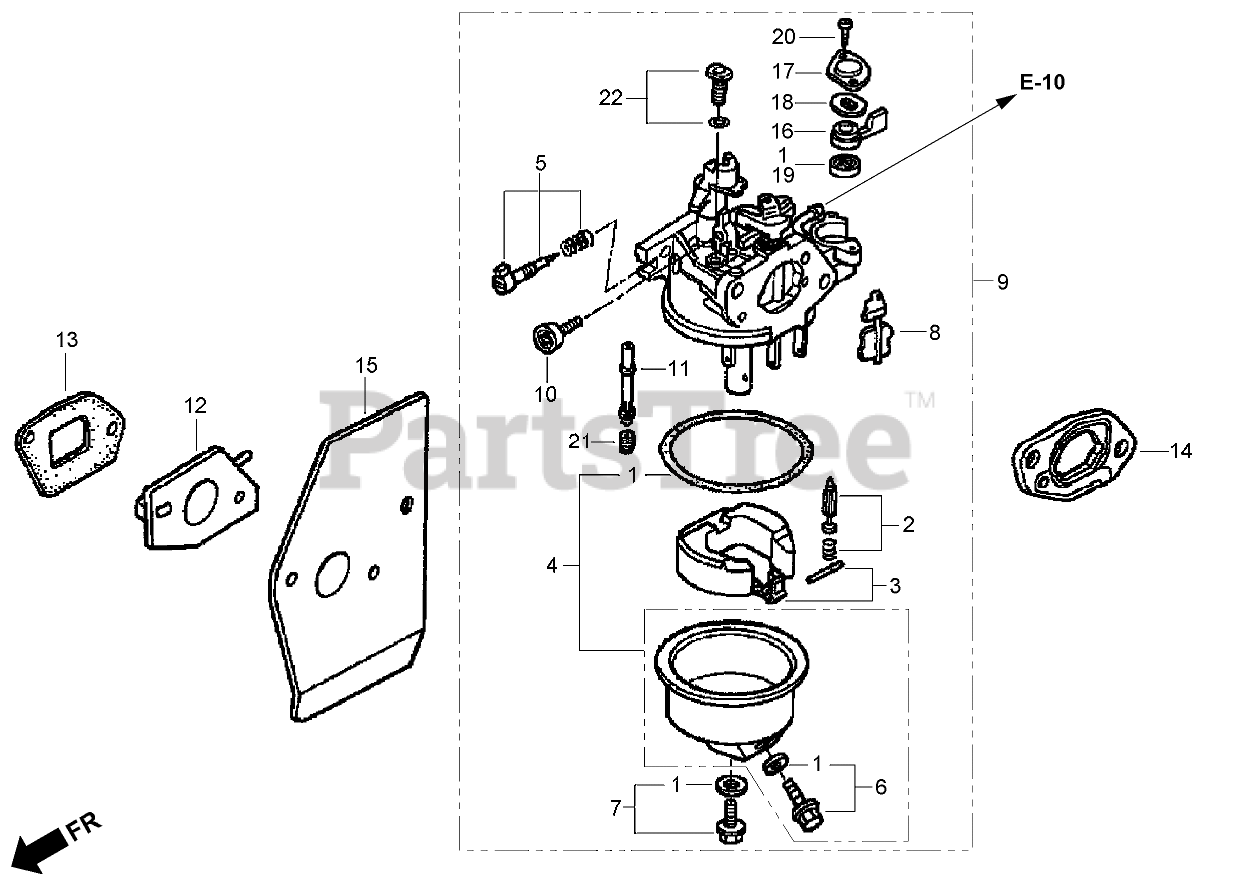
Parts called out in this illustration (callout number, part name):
1	GASKET SET
2	FLOAT VALVE SET
3	FLOAT SET (CARBURETOR NO. BE66J A)
3	FLOAT SET (CARBURETOR NO. BE66N A)
4	FLOAT CHAMBER SET
5	PILOT SCREW SET
6	DRAIN SCREW SET
7	SCREW SET
8	CHOKE SET (CARBURETOR NO. BE66J A)
8	CHOKE SET (CARBURETOR NO. BE66N A)
9	CARBURETOR ASM (BE66J A) (Engine Serial No. Up To 1001679)
9	CARBURETOR ASM (BE66N A) (Engine Serial No. From 1001680)
10	SCREW- STOP, THROTTLE
11	NOZZLE-MAIN (CARBURETOR NO. BE66J A)
11	NOZZLE-MAIN (CARBURETOR NO. BE66N A)
12	Insulator-Carburetor
13	Gasket-Insulator
14	Spacer-Carburetor
15	Gasket-Carburetor
16	LEVER-PETCOCK
17	PLATE-SETTING, LEVER
18	SPRING-LEVER, PETCOCK
19	GASKET-PETCOCK
20	SCREW-PAN (3X6)
21	JET-MAIN (No. 60) (CARBURETOR NO. BE66J A)
21	JET-MAIN (No. 62)
21	JET-MAIN (No. 65) (CARBURETOR NO. BE66J A)
21	JET-MAIN (No. 65) (CARBURETOR NO. BE66N A)
21	JET-MAIN (No. 68) (CARBURETOR NO. BE66N A)
22	PILOT JET SET (No. 35)
